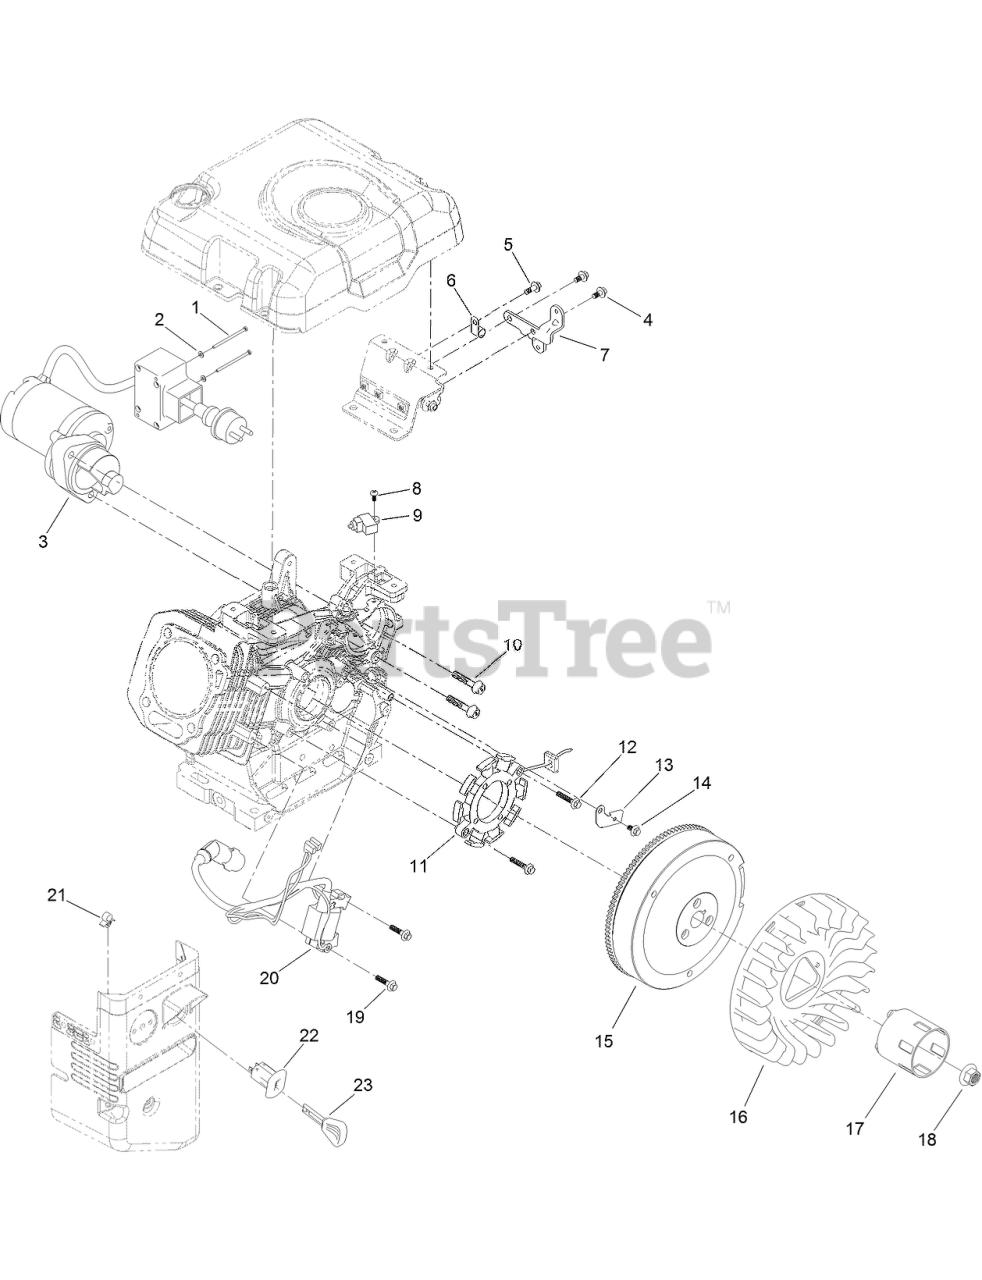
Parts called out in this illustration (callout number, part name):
1	SCREW-BHP
2	WASHER-PLAIN
3	MOTOR-STARTER
4	SCREW-HHF
5	SCREW-HHF
6	CLIP-HARNESS, WIRE
7	BRACKET-BOX, SWITCH
8	SCREW-PPH
9	SWITCH-STOP, ENGINE
10	SCREW-HHF
11	STATOR COIL ASM
12	SCREW-HHF
13	CLAMP-WIRE, CHARGE
14	SCREW-HHF
15	FLYWHEEL ASM
16	FAN-COOLING
17	CUP-STARTER
18	NUT-FLANGE
19	SCREW-HHF
20	IGNITION COIL ASM
22	SWITCH-KEY
